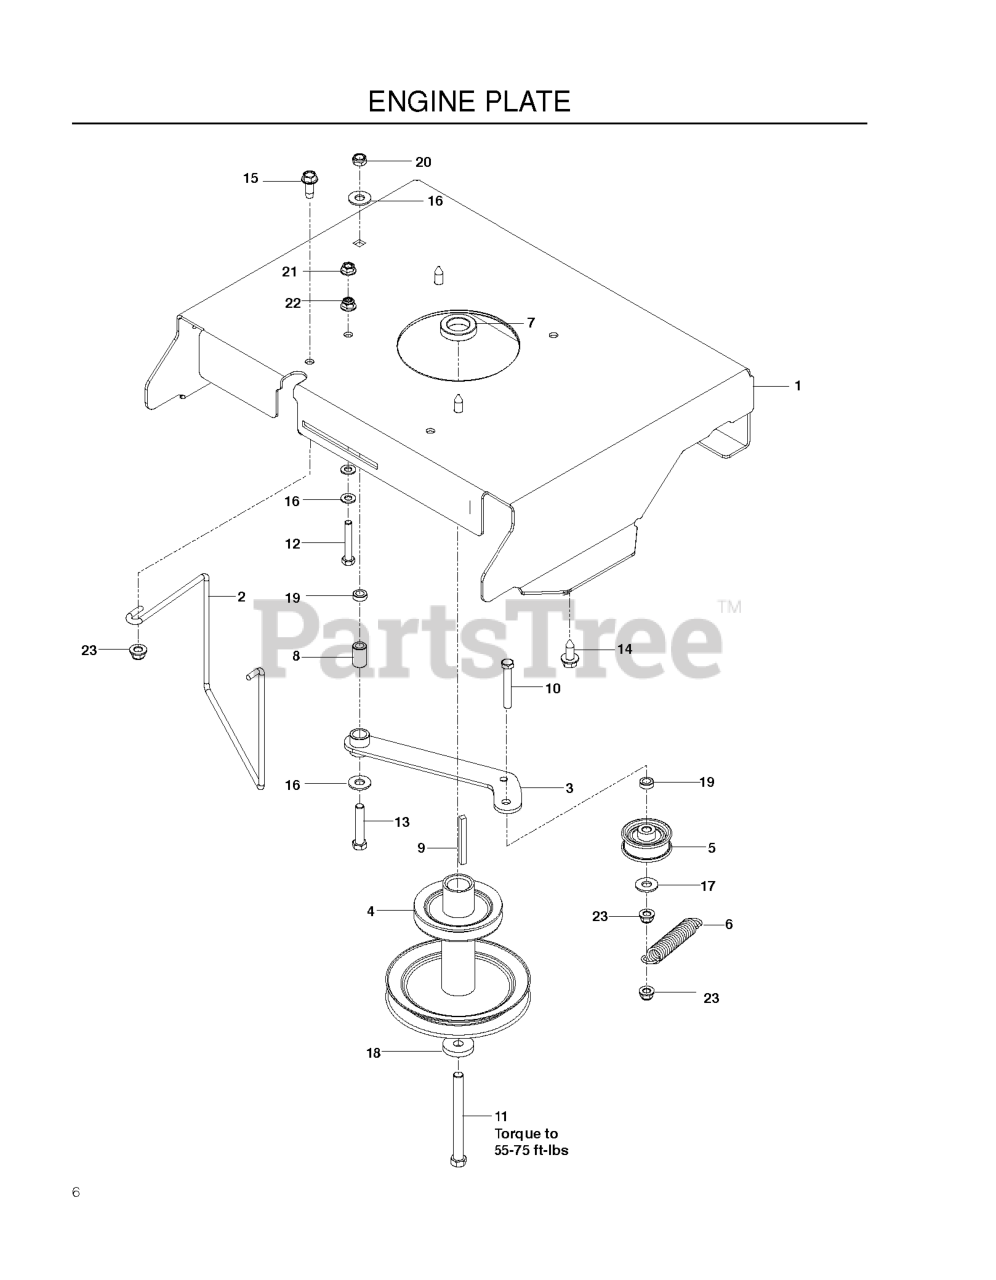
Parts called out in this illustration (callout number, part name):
1	PLATE.ENGINE.ORG
2	KEEPER, BELT ENGINE
3	!DLER ARM WLDMNT, BLACK
4	PULLEY IDLER
5	PULLEY, ENGINE 6.5
6	SPRING - 3.50
9	KEY 1/4 SQ X 2-1/2
10	TAPBOLT, 3/8C X 3
11	HCS 7/16-20 X 4 GR5 ZD
12	HCS 5/16-18X2
13	HCS 3/8C X 2
14	HHFS 3/8-16 X 1.0 THD FORMING
15	BOLT 3/8-16 X 1.0
16	FLAT WASHER 5/16 SAE
17	WASHER 3/8 FLAT
18	WASHER .43X1.38X.25
19	WASHER 3/8 X 3/4 X .187 TK
20	NUT HEX 3/8-16 NYLON, THIN
21	NUT 5/16C WHIZ
22	5/16-18 NYLOC FLANGE NUT
23	NUT 3/8-16 HEX FLG NYLOC ZD
